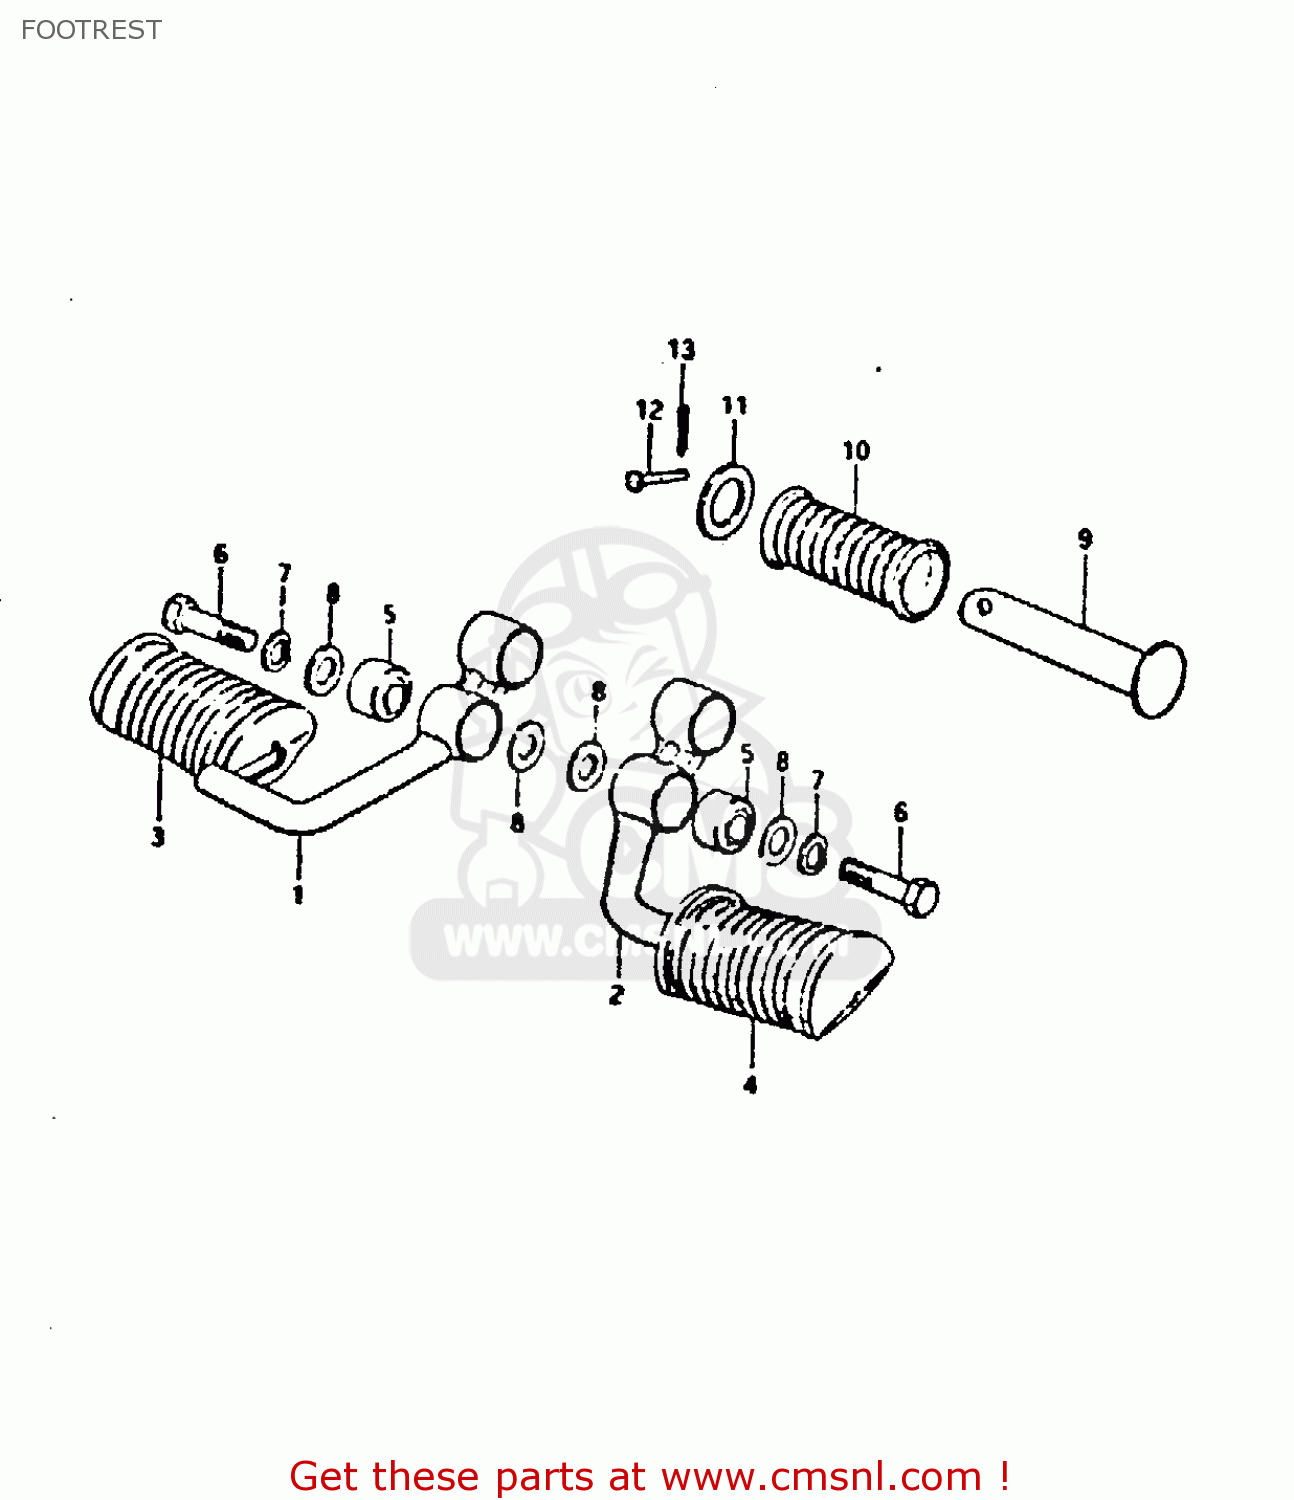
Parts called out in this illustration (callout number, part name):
1	BAR, FRONT FOOTREST RH
2	BAR, FRONT FOOTREST LH
3	RUBBER,FR.FOOT
4	RUBBER,FR FOOTREST
5	BUSH
6	BOLT 10X40
7	LOCK WASHER
8	WASHER (10.1X21X2.3)
9	BAR,FOOTREST RUBBER
10	RUBBER,PILLION FOOTREST
11	WASHER (19.5X32X2)
12	PIN
13	PIN 20X20
